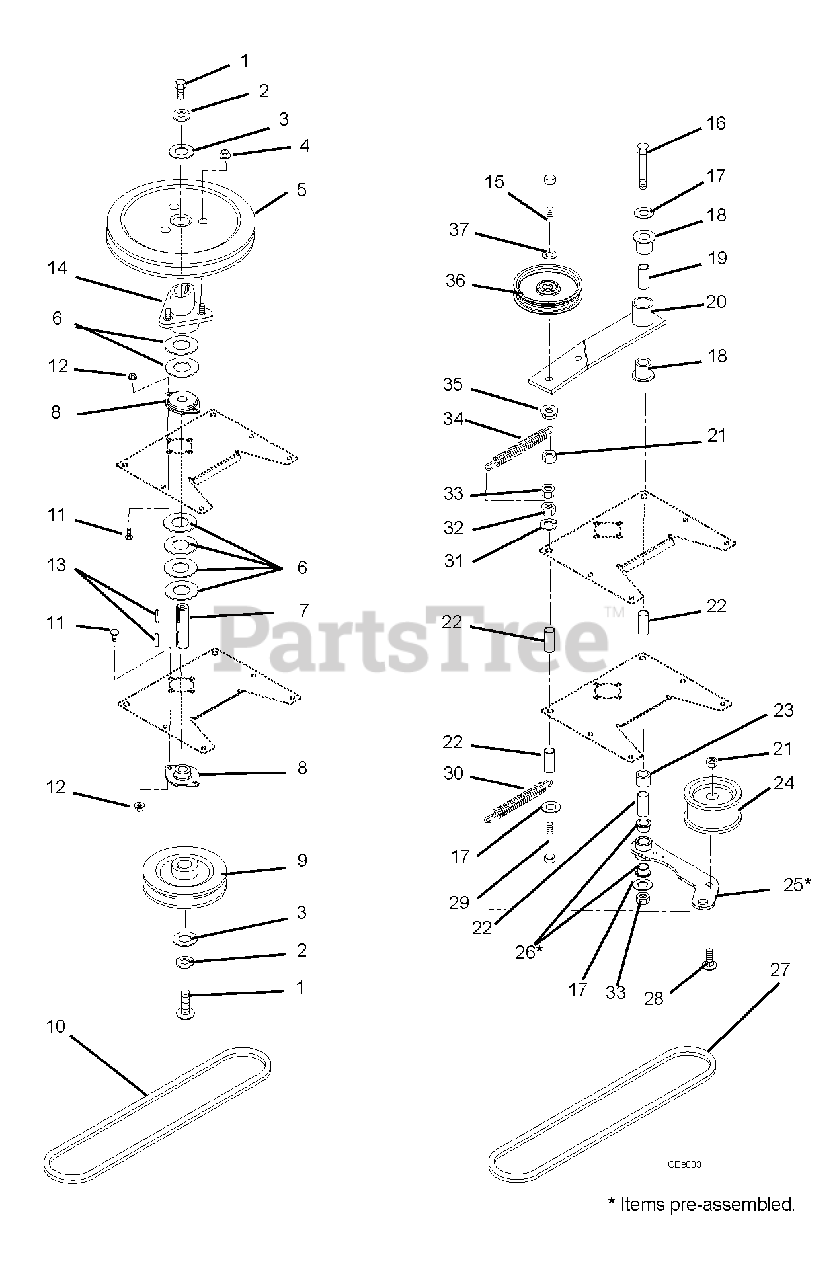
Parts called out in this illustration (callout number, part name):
1	Bolt, Hex .25-20 x .75 Grade 5
2	Washer, Locking .25 x .062 Regular
3	Washer, Flat Steel .344 x 1.125 x .135
4	Nut, Spin Lock-Flange .312-18
5	Pulley, V 9.0 x 1.25
6	Washer, Flat Steel .755 x 1.25 x .125
7	Shaft, Zoom Snow Throw
8	Bearing, 2 Bolt Flange-.75 ID
9	Sheave, Blower- 4.25 Diameter
10	V-Belt 4L-Section 56.45 x .516
11	Bolt, Round Head Square Neck .31-18 x .75 Grade 5
12	Nut, Locking Top Flange .31-18
13	Key Square .187 x .50 x .187 Hardened
14	Hub Assembly
15	Bolt, Hex .38-16 x 2.25 Grade 5
16	Bolt, Hex .50-13 x 7.00
17	Washer, Flat Steel .531 x 1.06 x .095
18	Bushing, Nylon, Flange .762 x 1.0 x .580 x 1.48
19	Bushing, Steel .560 x .745 x 2.04 Steel
20	Weldment, Idler
21	Nut, Locking-Jam-Center .375-16
22	Bushing-Sleeve .500 x .750 x 1.560
23	Bushing, .516 x 1.0 x 1.05
24	Idler Flanged 3.50
25	Weldment, Idler
26	Bushing, Flanged 0.75 x 0.875 x .625 x 1.125
27	V-Belt, 112.3
28	Bolt, Round Head Square Neck .38-16 x 1.75 Grade 5
29	Bolt, Hex .50-13 x 1.50 Grade 5
30	Spring, Extension
31	Washer, Locking .50 x .125
32	Nut, Hex .50-13
33	Nut, Locking Center Jam .500-13
34	Spring, Extension
35	Nut, Locking Jam Center .375-16
36	Pulley, Idler 4.00
37	Washer, Flat Steel .406 x .812 x .065
